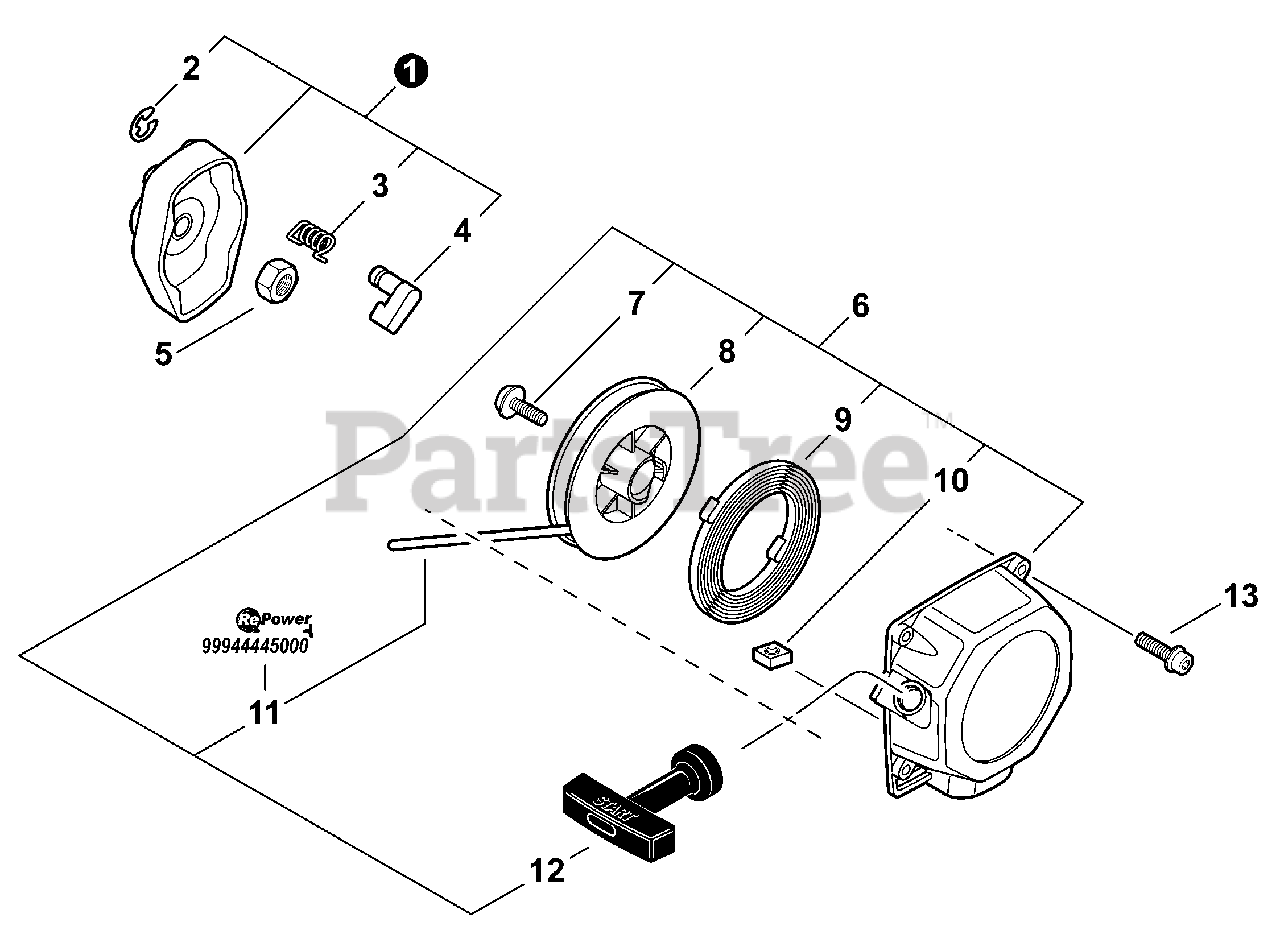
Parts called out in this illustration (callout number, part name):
1	PULLEY ASSY, STARTER
2	E-RING 4
3	SPRING, RETURN
4	PAWL, STARTER
5	NUT 8×1.25
6	STARTER, RECOIL
7	SCREW
8	REEL, ROPE
9	SPRING, RECOIL
10	NUT M5
11	ROPE, STARTER 3.5×900
12	GRIP, STARTER
13	SCREW 5×16
